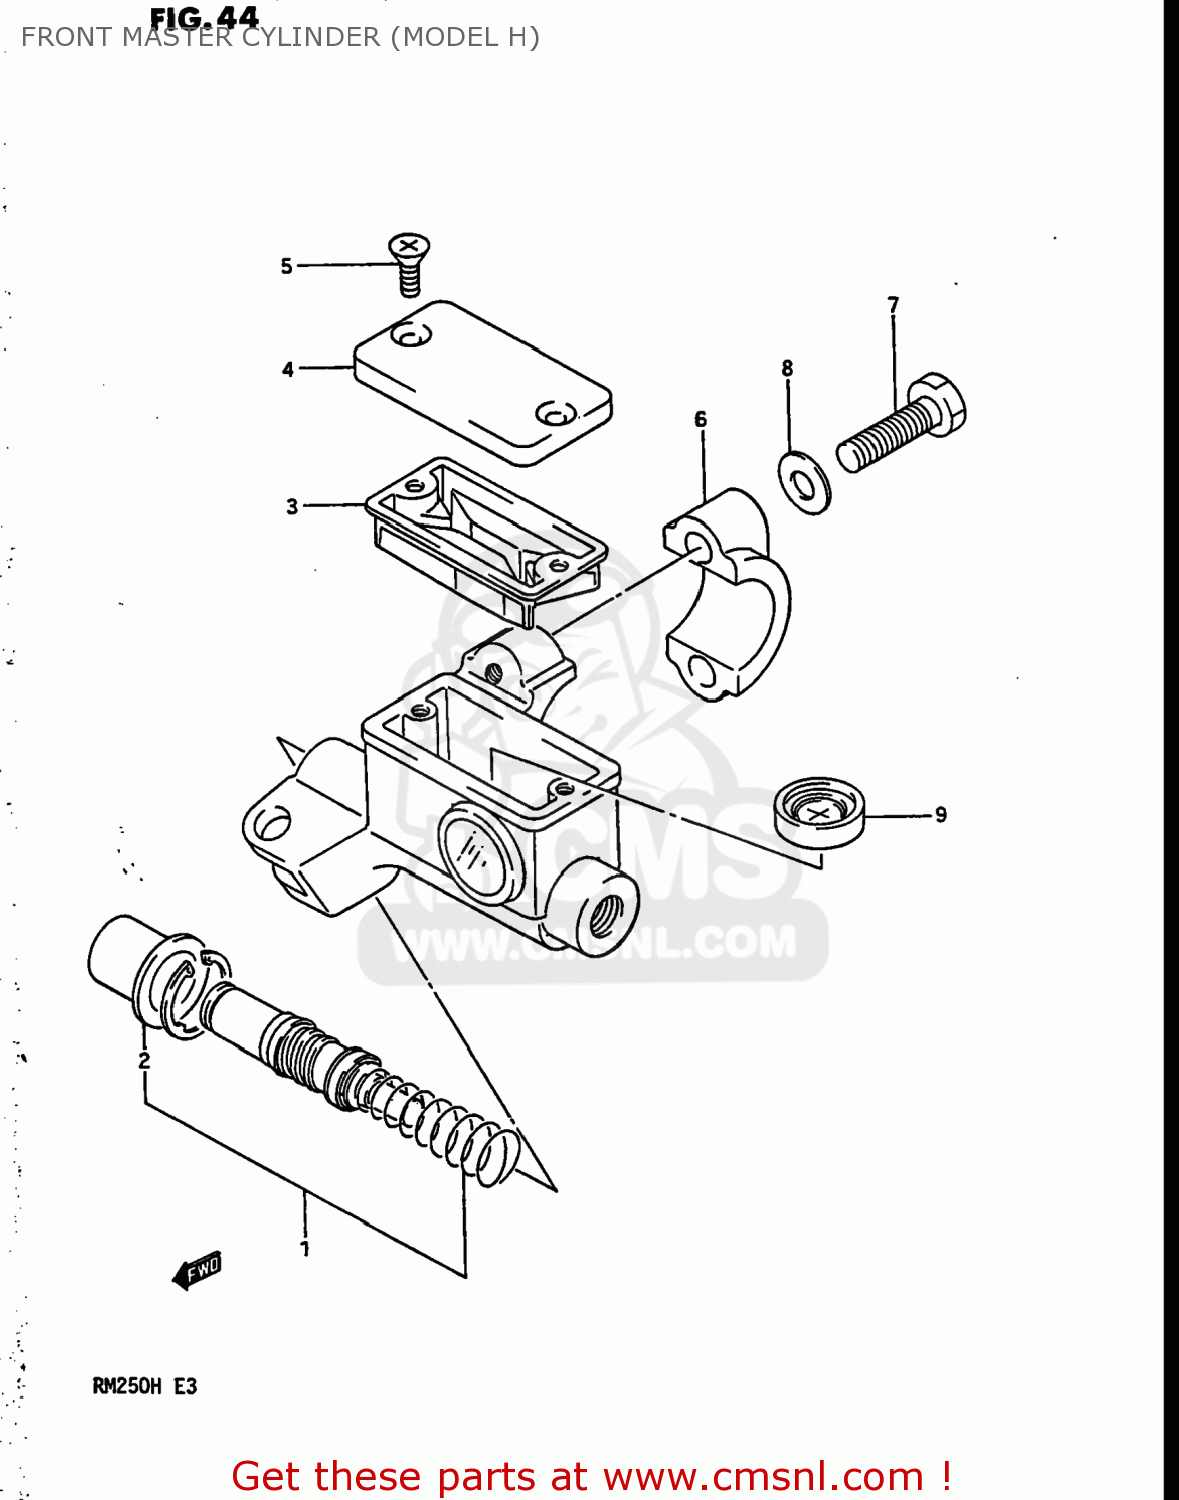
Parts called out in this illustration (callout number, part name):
1	PISTON & CUP SET
2	BOOT
3	DIAPHRAGM
4	CAP
5	SCREW
6	HOLDER,MASTER CYLINDER
7	BOLT
8	WASHER
9	SEPARATOR
